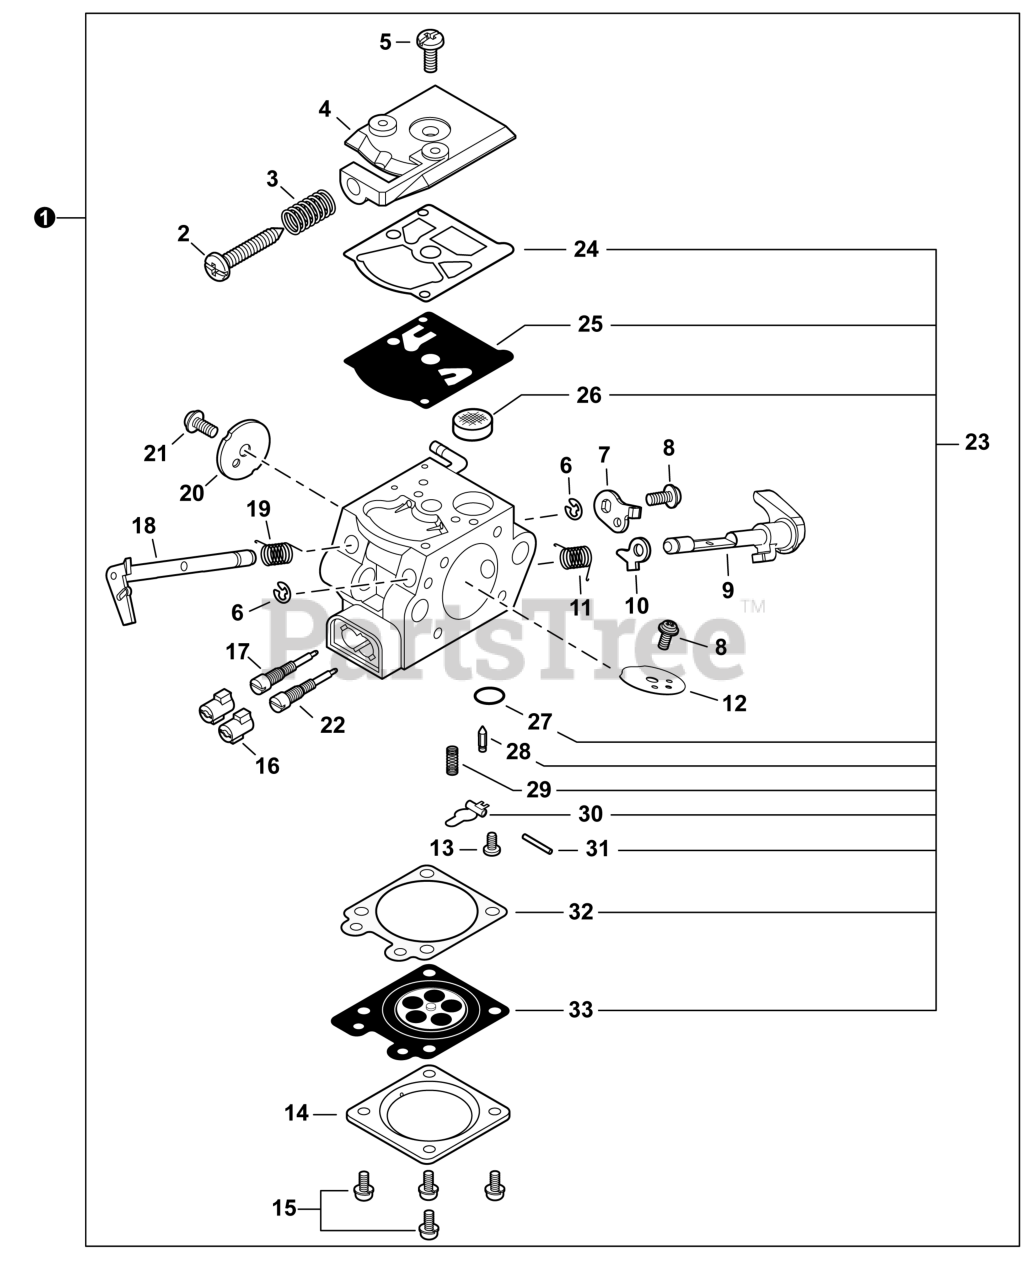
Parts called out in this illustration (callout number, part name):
1	CARBURETOR WT-1270
2	SCREW, IDLE ADJUST
3	SPRING, IDLE ADJUST
4	COVER, FUEL PUMP
5	SCREW
6	E-RING
7	LEVER, THROTTLE
8	SCREW
9	SHAFT ASSY, CHOKE
10	LEVER, FAST IDLE
11	SPRING
12	VALVE, CHOKE
13	SCREW
14	COVER, METERING DIAPHRAGM
15	SCREW
16	CAP, LIMITER
17	NEEDLE, MIXTURE
18	SHAFT, THROTTLE
19	SPRING, THROTTLE RETURN
20	VALVE, THROTTLE
21	SCREW
22	NEEDLE, MIXTURE
23	REPAIR KIT, CARBURETOR
24	GASKET, FUEL PUMP
25	DIAPHRAGM, PUMP
26	SCREEN, FUEL INLET
27	PLUG, WELCH
28	VALVE, INLET NEEDLE
29	SPRING, METERING LEVER
30	LEVER, METERING
31	PIN, METERING LEVER
32	GASKET, METERING DIAPHRAGM
33	DIAPHRAGM, METERING
